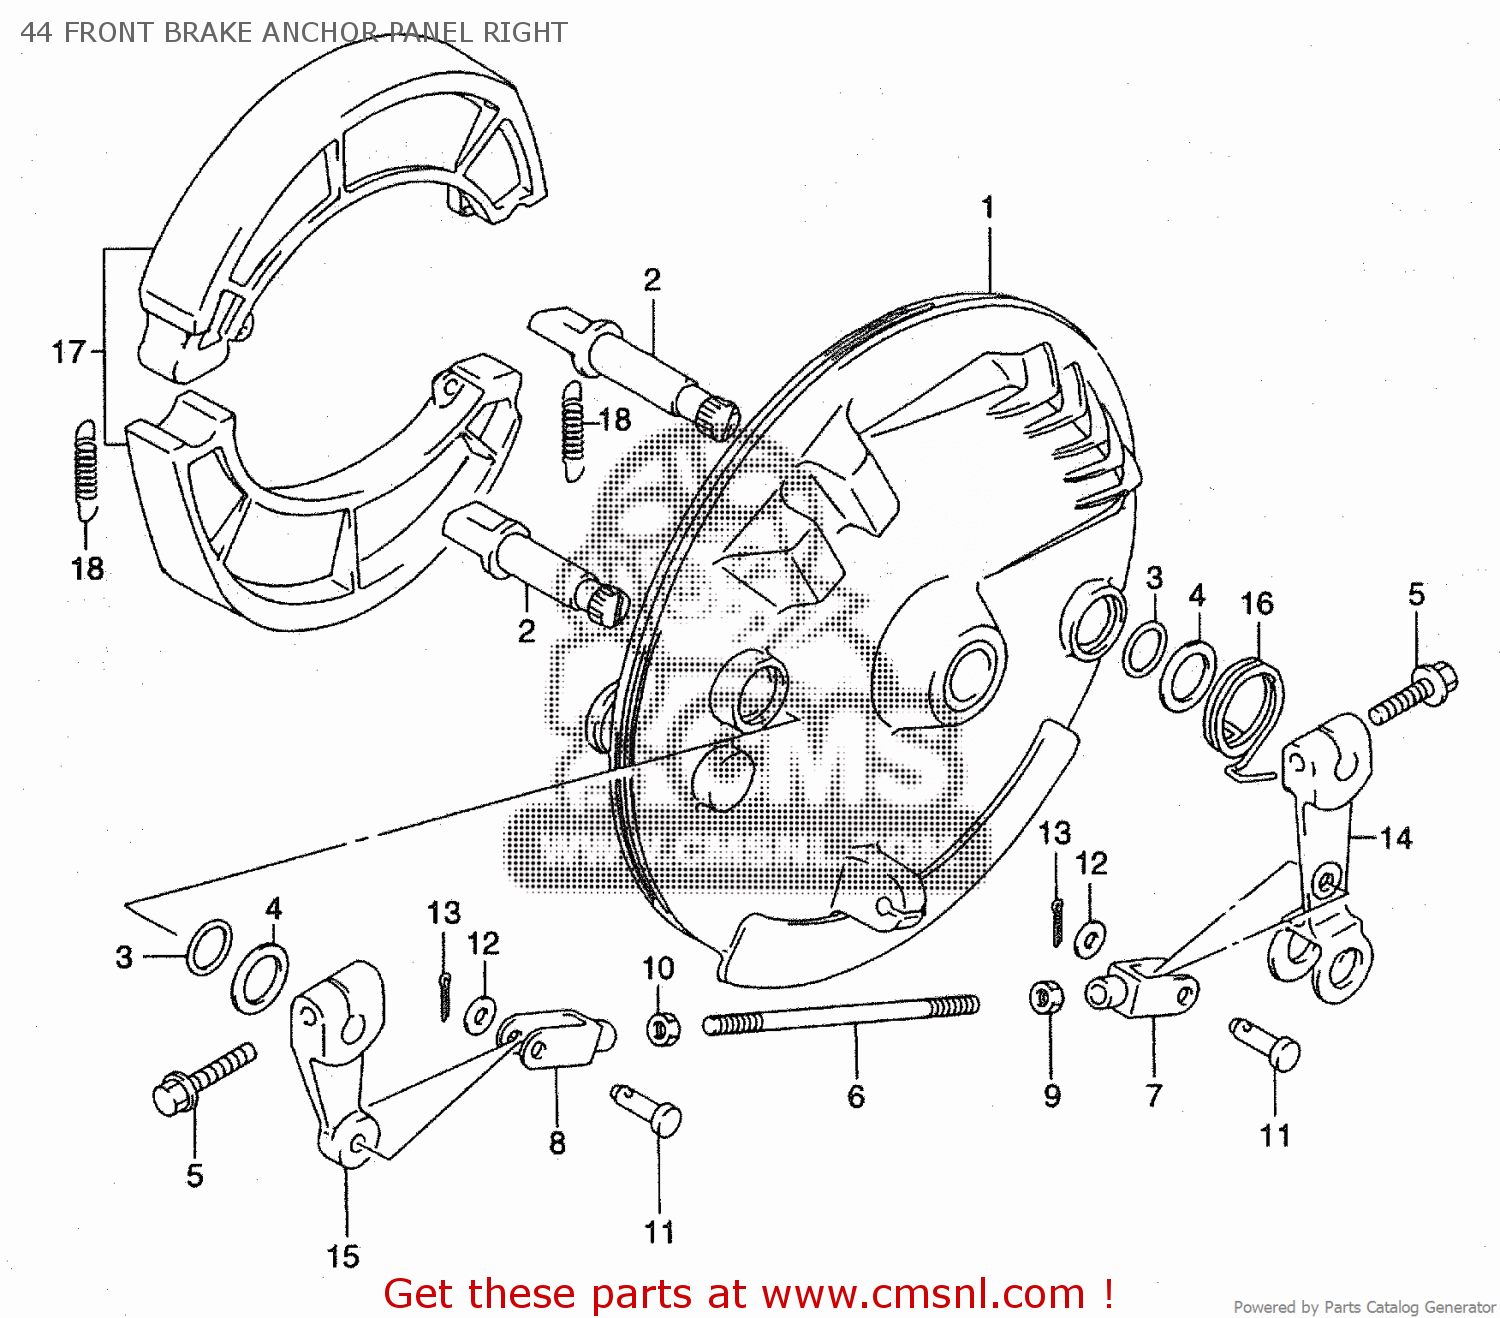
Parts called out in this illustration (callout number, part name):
1	COVER,FRONT HUB PANEL
2	CAM, FRONT BRAKE R/H
3	O RING(D:2.4,ID:14.8)
4	WASHER(15.5X24X1.6)
5	BOLT
6	CONNECTING ROD,BRAKE CAM LEVER
7	END,CAM LEVER CONNROD FR
8	END,CAM LEVER CONNROD RR
9	NUT
10	NUT
11	PIN
12	WASHER
13	PIN
14	LEVER,FR BRAKE CAM NO.1
15	LEVER,FR BRAKE CAM NO.2
16	SPRING,CAM LEVER RETURN,R
17	SHOE SET,FR BRAKE (NAS)
18	SPRING,BRAKE SHOE
